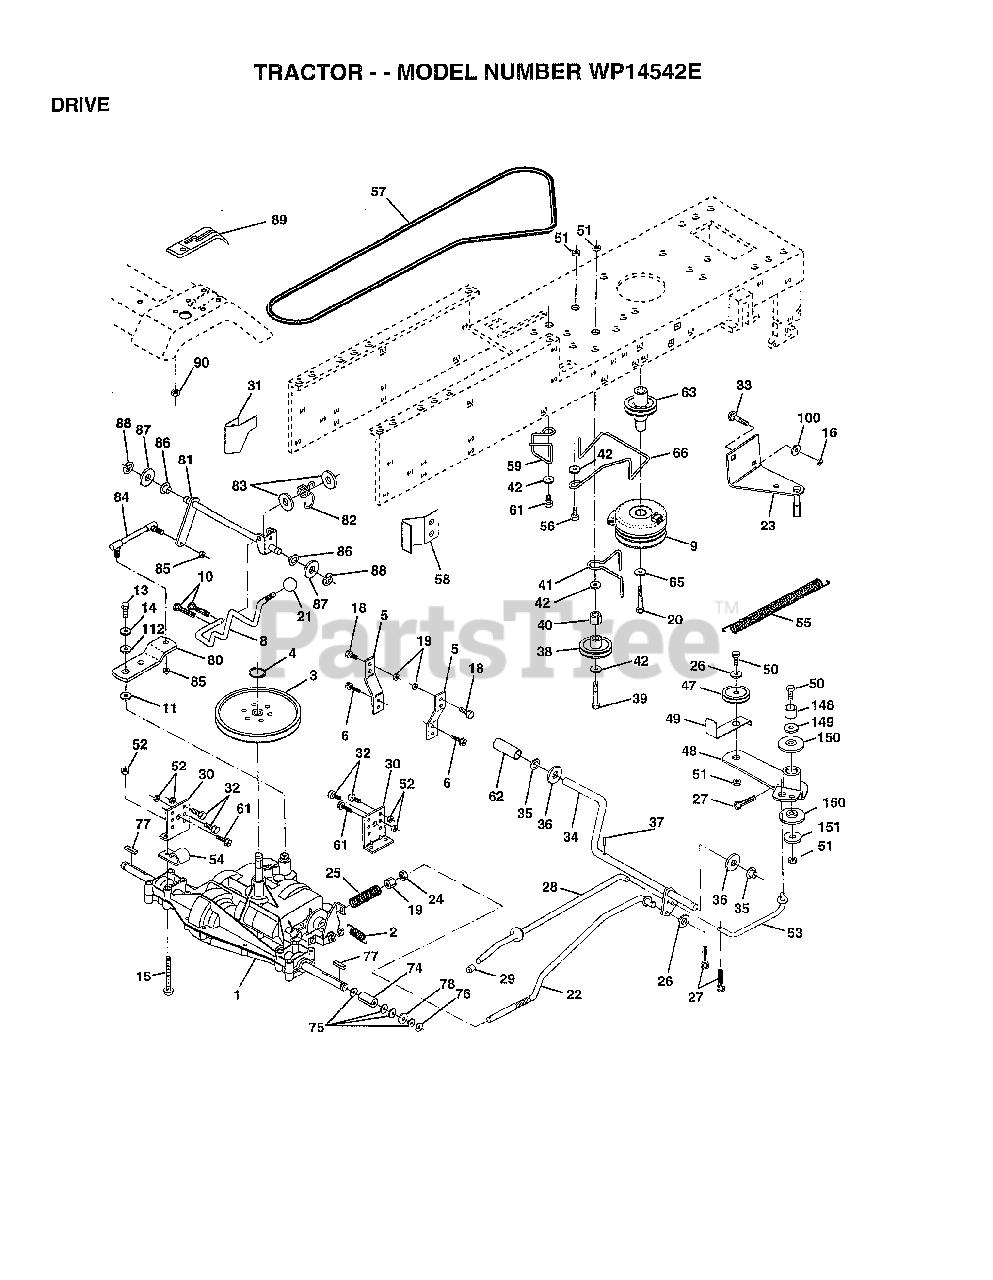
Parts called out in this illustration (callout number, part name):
1	TRANSAXLE ASM
2	SPRING.BRAKE.RETU
3	PULLEY TRANS
5	STRAP TORQUE
6	SCREW
8	ROD SHIFT FEND LT
9	CLUTCH.ELECT.EVX.
10	PIN COTTER 1/8
11	WASH-SHFT PLT LT
13	BOLT.1/4-28.W/PAT
14	LOCKWASHER
15	BOLT.HX.FLG.5/16
16	NUT
18	BOLT
19	NUT
20	BOLT.7/16-20X4.25
21	KNOB T (1/2-HOLE)
22	BRAKE ROD
23	BRACKET.CLUT.MTG.
24	NUT
25	SPRING ROD LT
26	WASHER
27	COTTER PIN
28	ROD.BRAKE.PARK.LT
29	PLUNGER CAP T
30	TRANSAXLE MTG BKT
31	"KEEPER,BELT LH T"
32	BOLT
33	BOLT
34	SHAFT ASM-PEDAL F
35	NYLON BEARING
36	WASHER LT
38	PULLEY.IDLER.FLAT
39	BOLT
40	SPACER T
42	WASHER
48	BELLCRANK.CLUTCH
49	RETAIN BELT
53	"LINK, CLUTCH T"
54	CLIP LINE FUEL
55	"SPRING, RETURN LT"
57	"V-BELT,95.3"
58	"KEEPER,BELT RH T"
59	KEEPER BELT CNTSP
61	SCREW
62	PEDAL COVER T
63	PULLEY.CLUTCH.EVX
65	LOCKWASHER
66	KEEPER-BELT
74	SPACER LT
76	E-RING LT
77	SQUARE KEY
78	WASHER
80	ARM.SHIFT.TRANS.
81	SHAFT ASSY CROSS
82	"SPRING,TORSION"
83	WASHER
84	"ROD.TIE.20""P930LT"
85	NUT.CNT.LOCK.1/4
86	BUSHING
87	WASHER D
88	KLIP RING
90	NUT
100	WASHER M
112	WASHER LT
149	SPACER RETAINER
150	BUSHING.NYLON
151	WASHER
